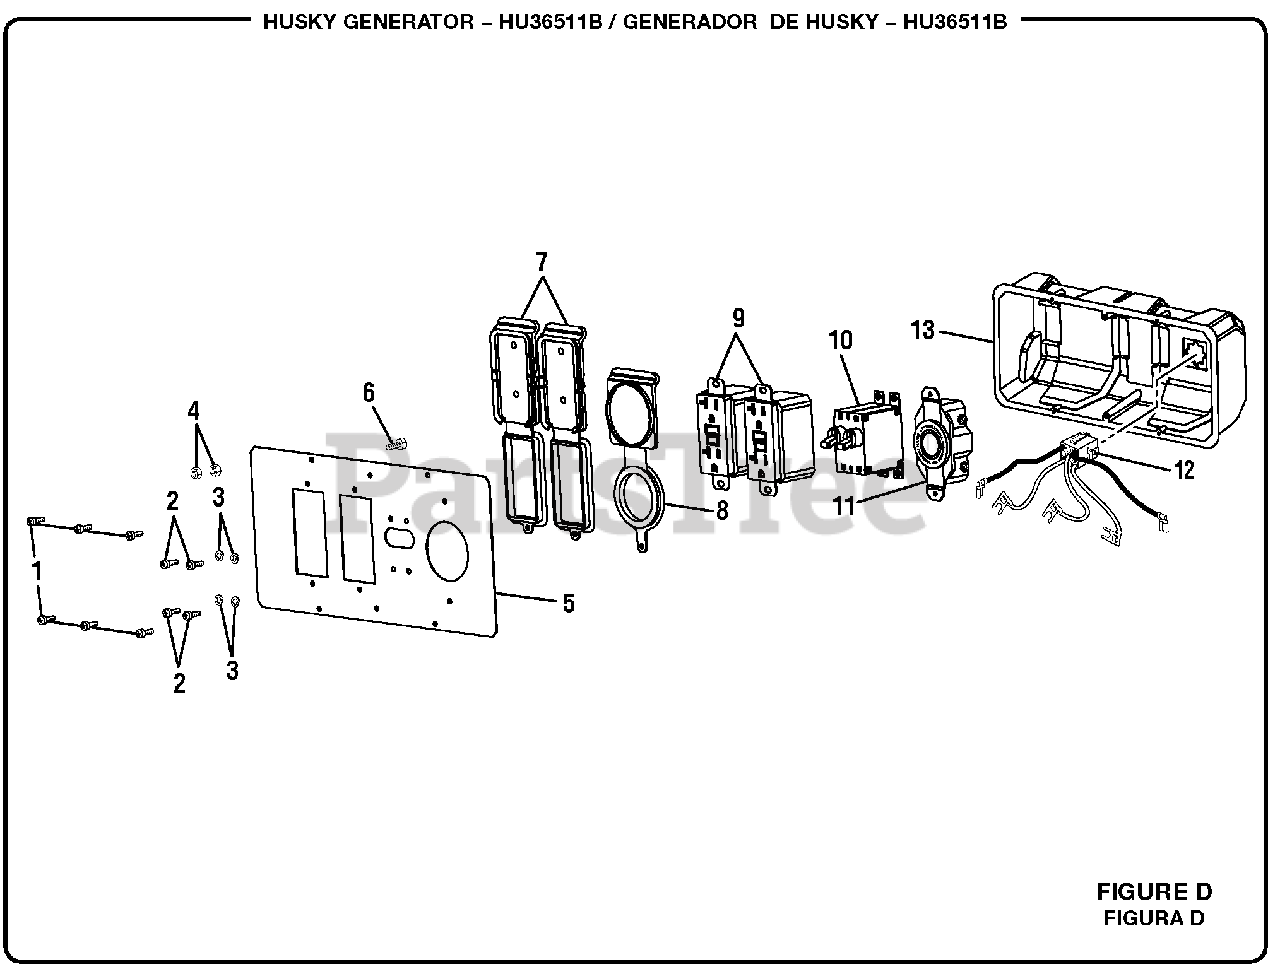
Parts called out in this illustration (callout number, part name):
1	Screw (6-20 x 3/8 in.)
2	Screw (M3 x 6)
3	Lock Washer
4	Hex Nut (1/4-20)
5	Cover Plate
6	Screw (1/4-20 x 5/8 in., Hex Hd.)
7	Outlet Cover (120 Volt)
8	Outlet Cover (240 Volt)
9	Duplex Receptacle (120 Volt)
10	Circuit Breaker
11	Twist Lock Receptacle (120/240 Volt, 20 Amp)
12	Connector w/Leads
13	Rear Control Panel
